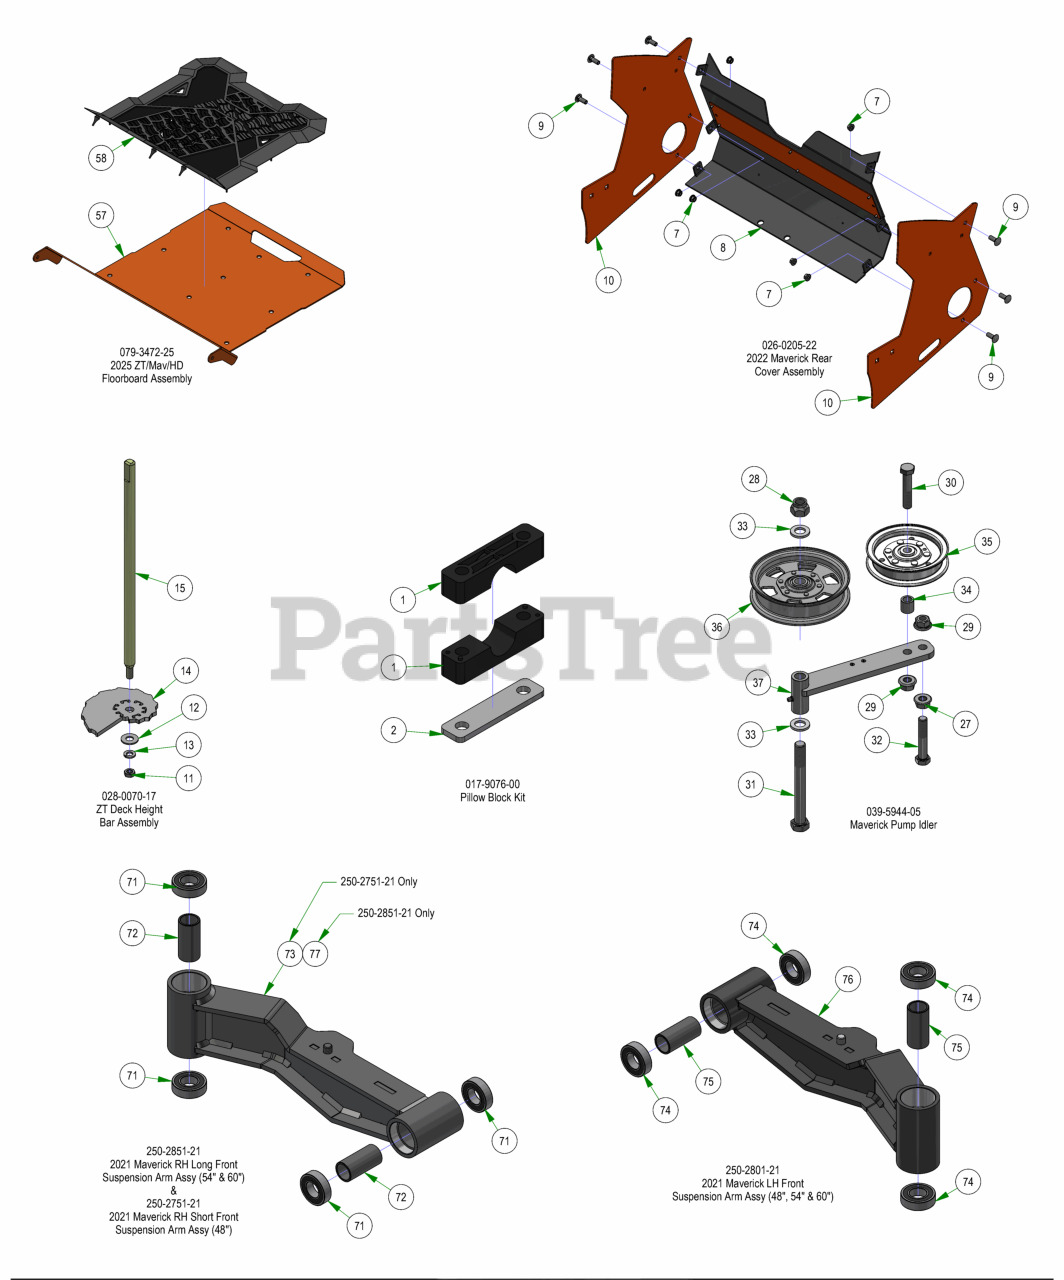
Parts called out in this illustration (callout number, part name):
1	Pillow Block MZ
2	Pillow Block Strap
3	5/16-18 NYLON INSERT FLANGE LOCKNUT ZINC
4	5/16-18 X 1 CARRIAGE BOLT (GR.8) ZINC
5	2017 MZ/ZT Shallow Foot Pedal
6	2017 MZ/ZT Deck Pedal Lever
7	5/16-18 NYLON INSERT FLANGE LOCKNUT ZINC
8	2021 Maverick Rear Cover Assembly
9	3/8-16 X 1 CARRIAGE BOLT (GR.5) ZINC
10	2022 Maverick Rear Cover Side Plate - Painted
11	3/8-24 HEX NUT ZINC YELLOW
12	3/8 FLAT WASHER USS (1" OD) ZINC
13	3/8 SPLIT LOCKWASHER ZINC
14	2017 MZ/ZT Cam Plate
15	2017 Deck Height Dial Rod ZT
16	3/8-16 Half Jam Nut
17	3/8-16 HEX SERRATED FLANGE NUT HARD/ZINC
18	3/8-16 X 2 HEX CAP SCREW (GR.5) ZINC
19	3/8 FLAT WASHER USS (1" OD) ZINC
20	Seat Spring
21	3/8-16 Half Jam Nut
22	3/8-16 HEX SERRATED FLANGE NUT HARD/ZINC
23	3/8-16 X 2 HEX CAP SCREW (GR.5) ZINC
24	3/8 FLAT WASHER USS (1" OD) ZINC
25	Seat Spring
26	Seat Strap with Buckles
27	1/2-13 HEX SERRATED FLANGE NUT HARD/ZINC
28	5/8-11 NYLON INSERT LOCKNUT ZINC
29	1/2-13 NYLON INSERT FLANGE LOCKNUT ZINC
30	1/2-13 X 2-1/2 HEX CAP SCREW GR 5 ZINC
31	5/8-11 X 5-1/2 HEX CAP SCREW (GR.5) ZINC
32	1/2-13 X 2-3/4 HEX CAP SCREW (GR.5) ZINC
33	.635 ID X 1.120 OD X .140 THICK FLAT WASHER NYLON
34	.51 ID X .75 OD X .75 LGTH SOLID SPACER ZINC
35	4 3/4" Idler Pulley
36	5 3/4 Idler Pulley, 5/8 Bore
37	Deck Idler
38	3/8-16 HEX JAM 2-WAY REVERSIBLE CENTER LOCKNUT ZINC
39	5/16-18 NYLON INSERT CAP LOCKNUT ZINC (BLK CAP)
40	5/16-18 NYLON INSERT FLANGE LOCKNUT ZINC
41	5/16-18 HEX SERRATED FLANGE NUT HARD/ZINC
42	3/8-16 X 1-1/4 CARRIAGE BOLT ZINC
43	5/16-18 X 1 CARRIAGE BOLT (GR.8) ZINC
44	3/8 FLAT WASHER USS (1" OD) ZINC
45	2015 Brake Lever Spacer
46	.377 ID X .625 OD X .500 HGT X .880 FLNG DIA X .060 FLNG THK BUSHING
47	Brake Cable Extension Plate
48	Brake Load Balancer Lower Weldment
49	Load Balanced Brake Handle with Grip
50	Back Cover 2024 Maverick Digital Seat
51	Seat Cover 2024 Maverick Digital Seat
52	Extended Pin (Poly Pad) Arms Pair 2024 Maverick
53	Seat Slide 6.5" Latch Slid w/3 holes 2024 Maverick
54	Seat Slide (Slave) w/3 holes 2024 Maverick
55	Seat Belt Assembly for 2024 Maverick Digital Seat
56	13/14 MZ/Outlaw Seat Switch
57	2025 Elite Maverick Floorboard
58	25 Mav Floor Mat. V4
59	Ignition Switch
60	10-24 NYLON INSERT LOCKNUT ZINC
61	Light Plug
62	10-24 X 5/8 BUTTON SOCKET CAP SCREW 18-8 STAINLESS STEEL
63	Throttle Lever Assembly
64	PTO Engager
65	4-Way Key Switch
66	2022 Maverick HD control panel
67	Tachometer
68	2023 MZ/Magnum/ZT/Maverick Control Panel Decal
69	Relay Block Cover Replacement Kit
71	1641 BEARING W/2 CONTACT RUBBER SEALS
72	2016 Front Bearing Spacer
73	2021 Maverick I-Beam Front Arm RH Short Weldment - Painted
74	1641 BEARING W/2 CONTACT RUBBER SEALS
75	2016 Front Bearing Spacer
76	2021 Maverick I-Beam Front Arm LH Weldment - Painted
77	2021 Maverick I-Beam Front Arm RH Long Weldment - Painted
